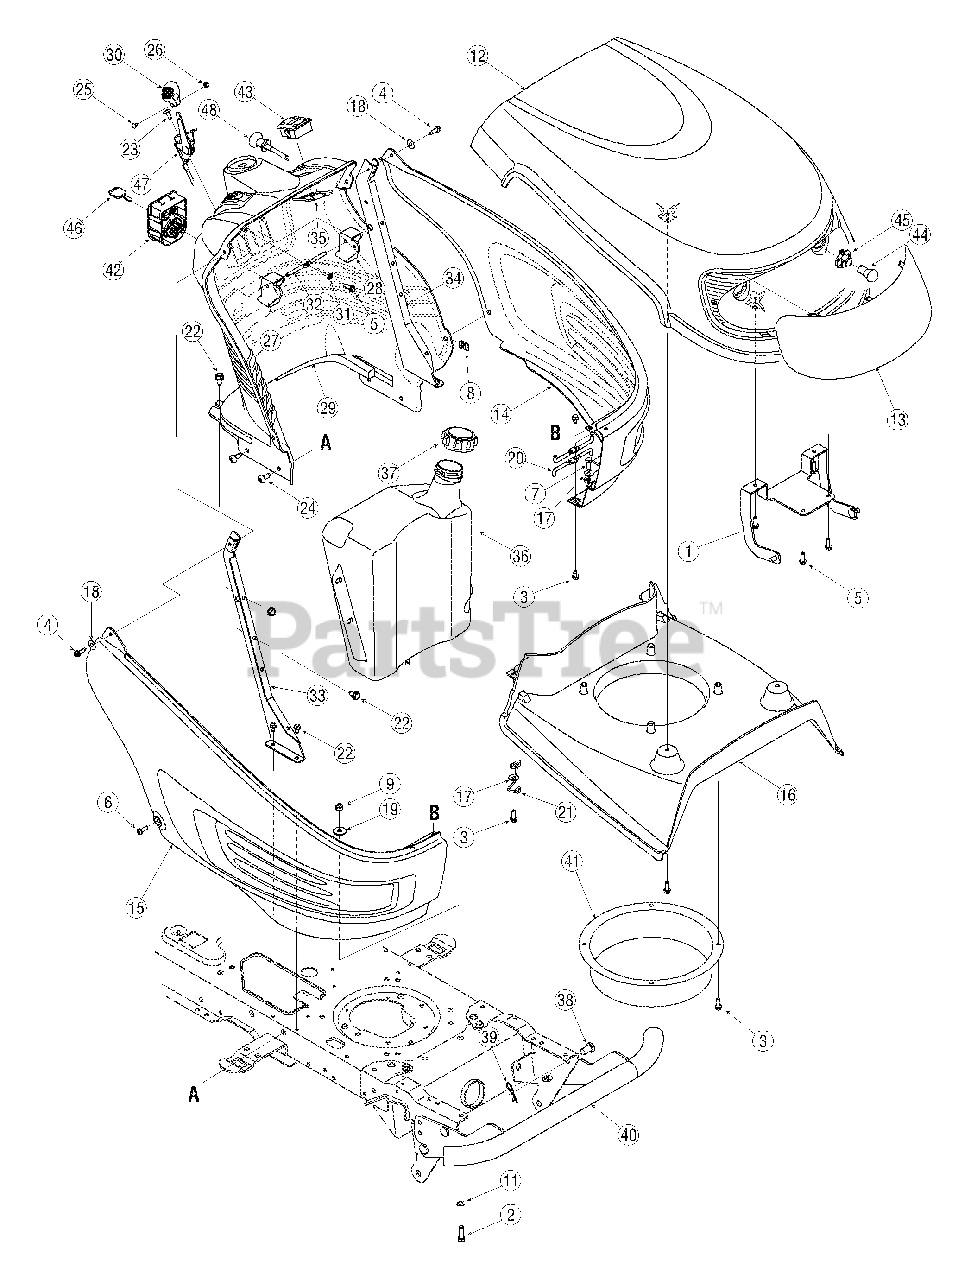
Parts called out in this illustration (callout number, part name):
3	Screw, 1/4-20, 0.500
4	Screw, 1/4-20, 0.750
5	Screw, 1/4-15, 0.750
6	Screw, Machine, 1/4-20, 0.750
7	Hex Screw, 1/4-20,.75, Gr5
8	Nut, Clip, 1/4-20
9	Nut, Flange Lock, 5/16-18, Grf, Nylon
10	Nut, Flange Lock, 1/4-20, Grf, Nylon
11	Nut, Speed, .3125 ID
12	Hood
13	Lens
14	Side Panel, LH
15	Side Panel, RH
17	Washer, Flat, .28 x .74 x .063
18	Washer, Flat, .283 x .75 x .030
19	Washer, Flat, .344 x 1.0 x .063
20	Support, Side Panel
21	Rod, Hood Latch
22	Screw, 5/16-12, 0.750
23	Screw, 1/4-14, 0.625
24	Screw, 5/16-18, 0.750
25	Screw, Machine, #8-32, 0.375
26	Nut, Hex, #8-32
28	Cruise Control Lever
29	Dash Panel (Models w/ Electric PTO)
30	Control Knob
31	Washer, Flat, .281 x .50 x .063
32	Rod, Brake / Cruise Pivot
35	Retainer Bracket, PTO Switch
36	Fuel Tank, 3 Gal.
37	Fuel Cap
38	Pin, Clevis, .50 x .78
39	Pin, Click, .092 x 1.64
40	Bumper
42	Ignition Switch Module
43	Systems Indicator Monitor w/ Hour Meter
44	Miniature Lamp, 12V
45	Socket, Lamp
46	Key, Ignition
47	Throttle Cable, 39"
48	Choke Knob w/ Cable, 37.5"
